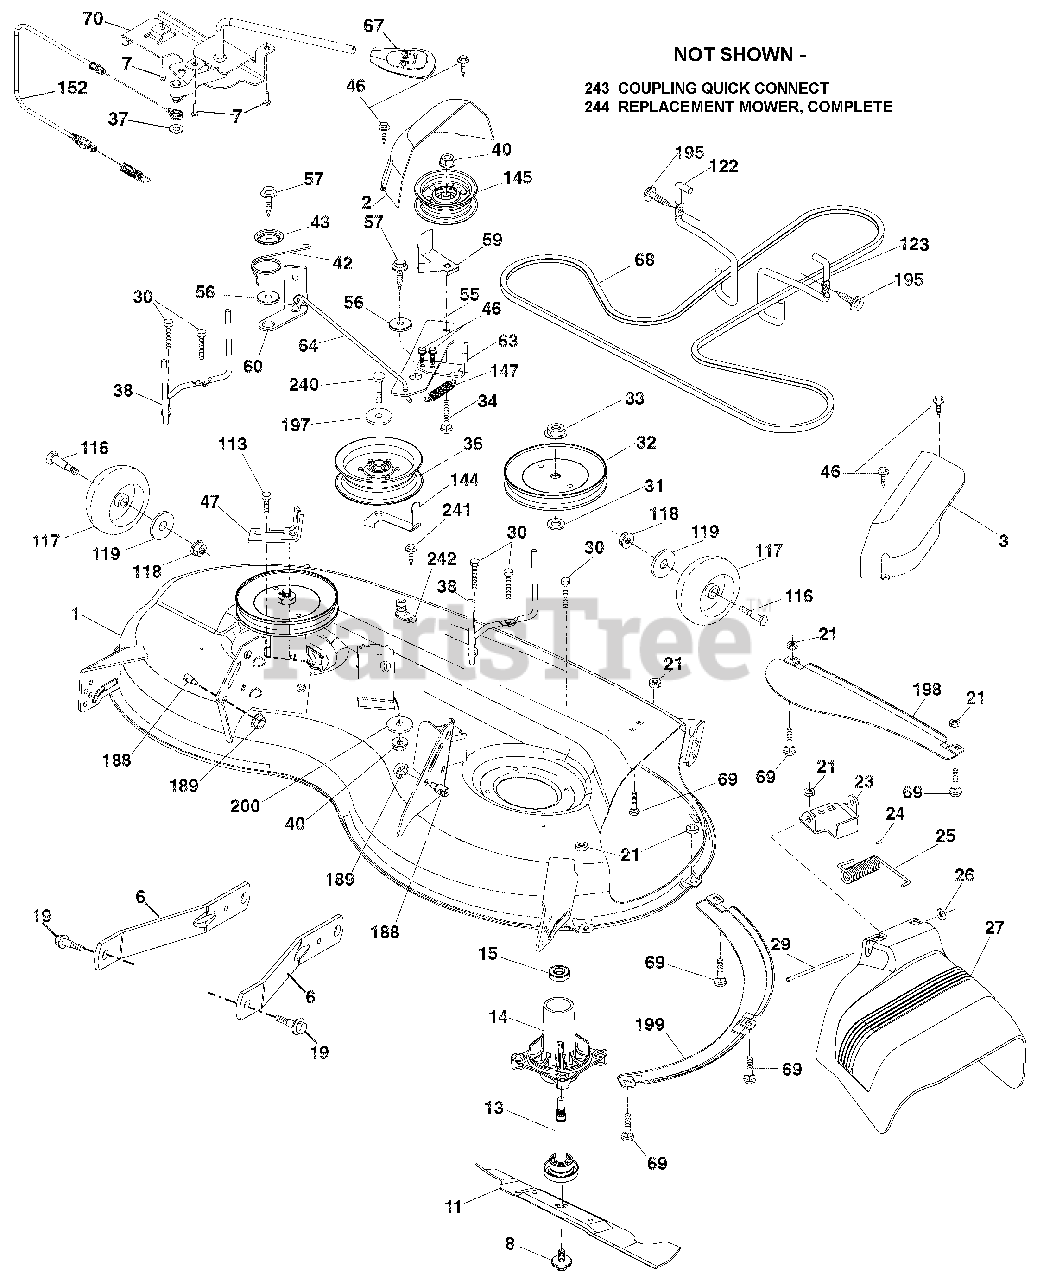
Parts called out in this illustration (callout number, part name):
1	MOWER HOUSING
2	COVER.MANDREL.LH.46"
3	COVER.MANDREL.RH.46"
6	ARM.SUSPENSION.MOWER.REAR.LD
8	BOLT/WASHER ASM.7/16-20.UNF
11	BLADE.MOWER.46"HI LIFT BAGGER
13	SHAFT ASM.MNDRL.N/GREASEABLE38
14	HOUSING.MANDREL.4PT.SERVICE
15	BEARING.BALL.MANDREL
19	BOLT.SHOULDER
21	Nut, Hex, Crownlock 5/16-18
23	BRACKET.DEFLECTOR.38/42"2005
24	CAP.SLEEVE..80X.112.BLK.MOWER
25	SPRING.TORSION.DFL.38/42/46.GR
26	NUT.PUSH.PHOS.& OIL
27	SHIELD.DEFLECTOR.MOWER 46"BLK
29	ROD.HINGE.42/46"
30	SCREW.THD ROLL.DOD PT.HEX
31	WASHER.SPACER.MANDREL
32	PULLEY.MANDREL.5.438 PD.42"
32	MANDREL ASM.SUB.N-GRS.4 BOLT
32	PULLEY/NUT/WASHER AND BLADE BOLT/WASHERS NOT INCLUDED)
33	NUT.FLANGE.LOCK.TOP
34	BOLT.CARR.SH.3/8-16X1-1/2.GR5
36	PULLEY.IDLER.4.50.RAW
37	WASHER.13/32 X 13/16 X 16 GA.
38	KEEPER.BELT.MANDREL.PULLEY
40	Nut, Hex, Flangelock 3/8-16
42	SPRING.TORSION.BRAKE
43	SPRING.TORSION.RETAINER
46	SCREW.THD.ROLL.1/4-20 X 5/8
47	BRACKET.CLUTCH.CABLE
55	IDLER.ARM
56	SPACER.RETAINER
57	SCREW.3/8-16X1.SMGML.TAP/R.BLK
59	GUARD.TUV.IDLER
60	ARM.BRAKE.MOWER.38/46"LH.TEX
63	ARM.BRAKE.MOWER
64	LINKAGE ASM.BRAKE.CLEAR ZINC
67	HANDLE.CLUTCH.CABLE.LT TEX.428
68	V-BELT.DRIVE.MWR.MECHANICL.46"
69	BOLT.RDHD.SQNK.5/16-18 X 5/8
70	CLUTCH ASM.
113	BOLT.5/16-18HEX.WHS.HD.LCKSERR
116	BOLD SHLD "A" 2.41 "B" 1.66
117	WHEEL.GAGE.HALF.SPOKED
118	Nut, Hex, Flangelock 3/8-16
119	Washer 3/8 x 7/8 x 14 Ga.
122	KEEPER.BELT.ENGINE.LH.LT.TEX
123	KEEPER.BELT.ENGINE.RH.LT.TEX
144	KEEPER.BELT.MOWER
145	PULLEY.IDLER 48"PRIMARY
147	SPRING.RETURN.DECK.38/46"
152	CABLE CLUTCH MANUAL W/SPR.
188	STUD.FASTNER.W/'D'ANTI-ROTATIO
189	Nut, Lock Hex Flange 5/16-18 u
195	SCREW.HEXWSH THDR3/8-16X3/4.BL
197	Washer 13/32 x 13/16 x 12 Ga.
198	BAFFLE.CENTER.FRONT
199	BAFFLE.FRONT.RH
200	WASHER.13/32 X 1 X 1/2.11GAHRD
240	BOLT.FIN.HEX.3/8-16X 2-1/4 GR5
242	PORT WASHOUT
